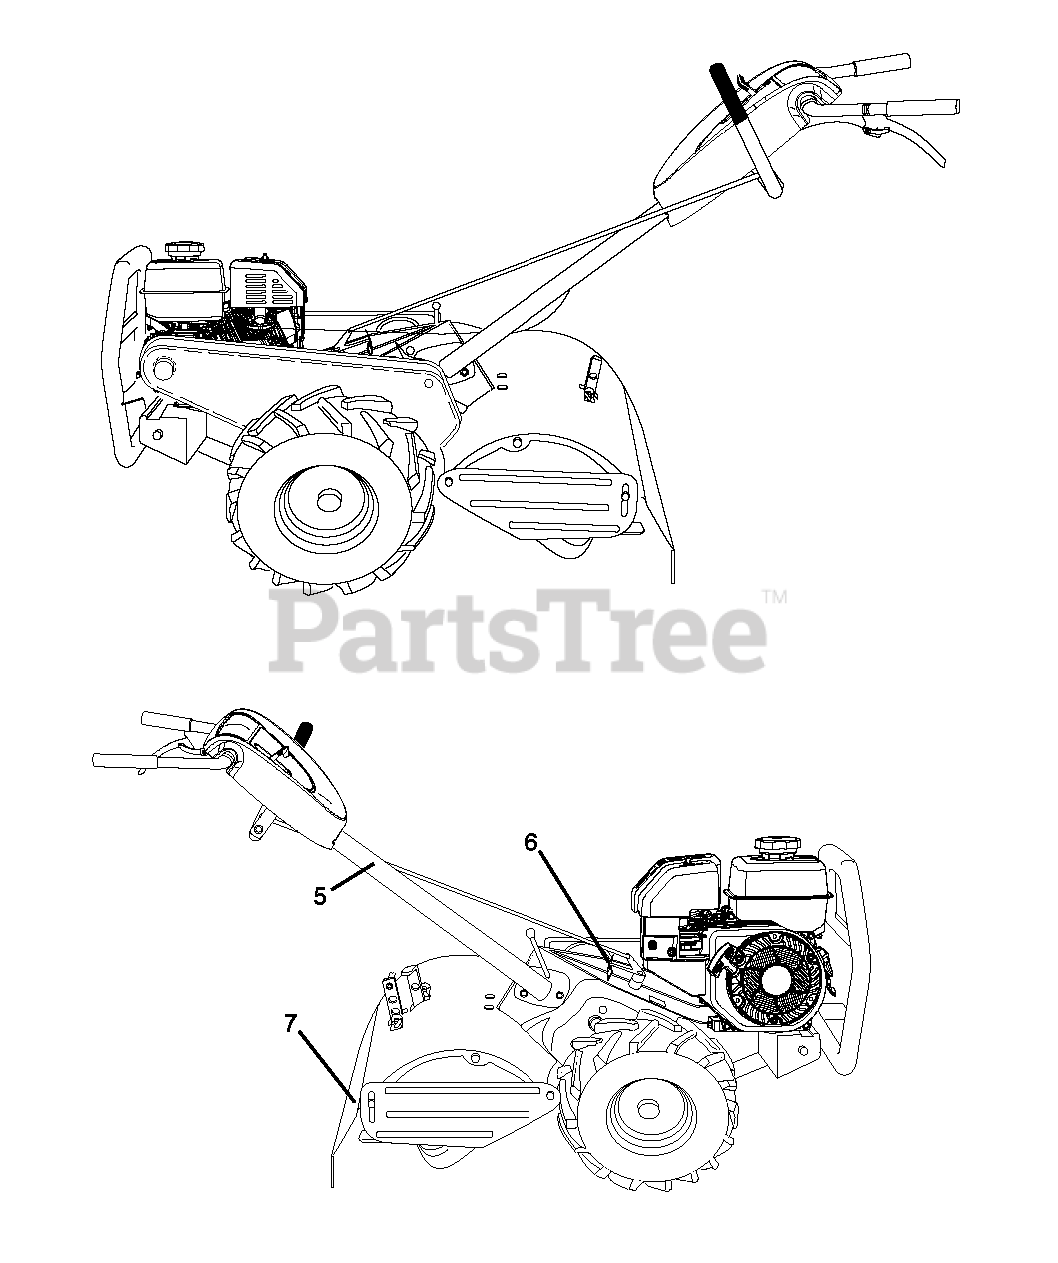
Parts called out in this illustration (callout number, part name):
5	DECAL.PLACEMENT.HAND.SYMBOLS
6	DECAL, SHIFT INDICATOR
7	DECAL.WARNING.4-SYM.TILLER.INT
